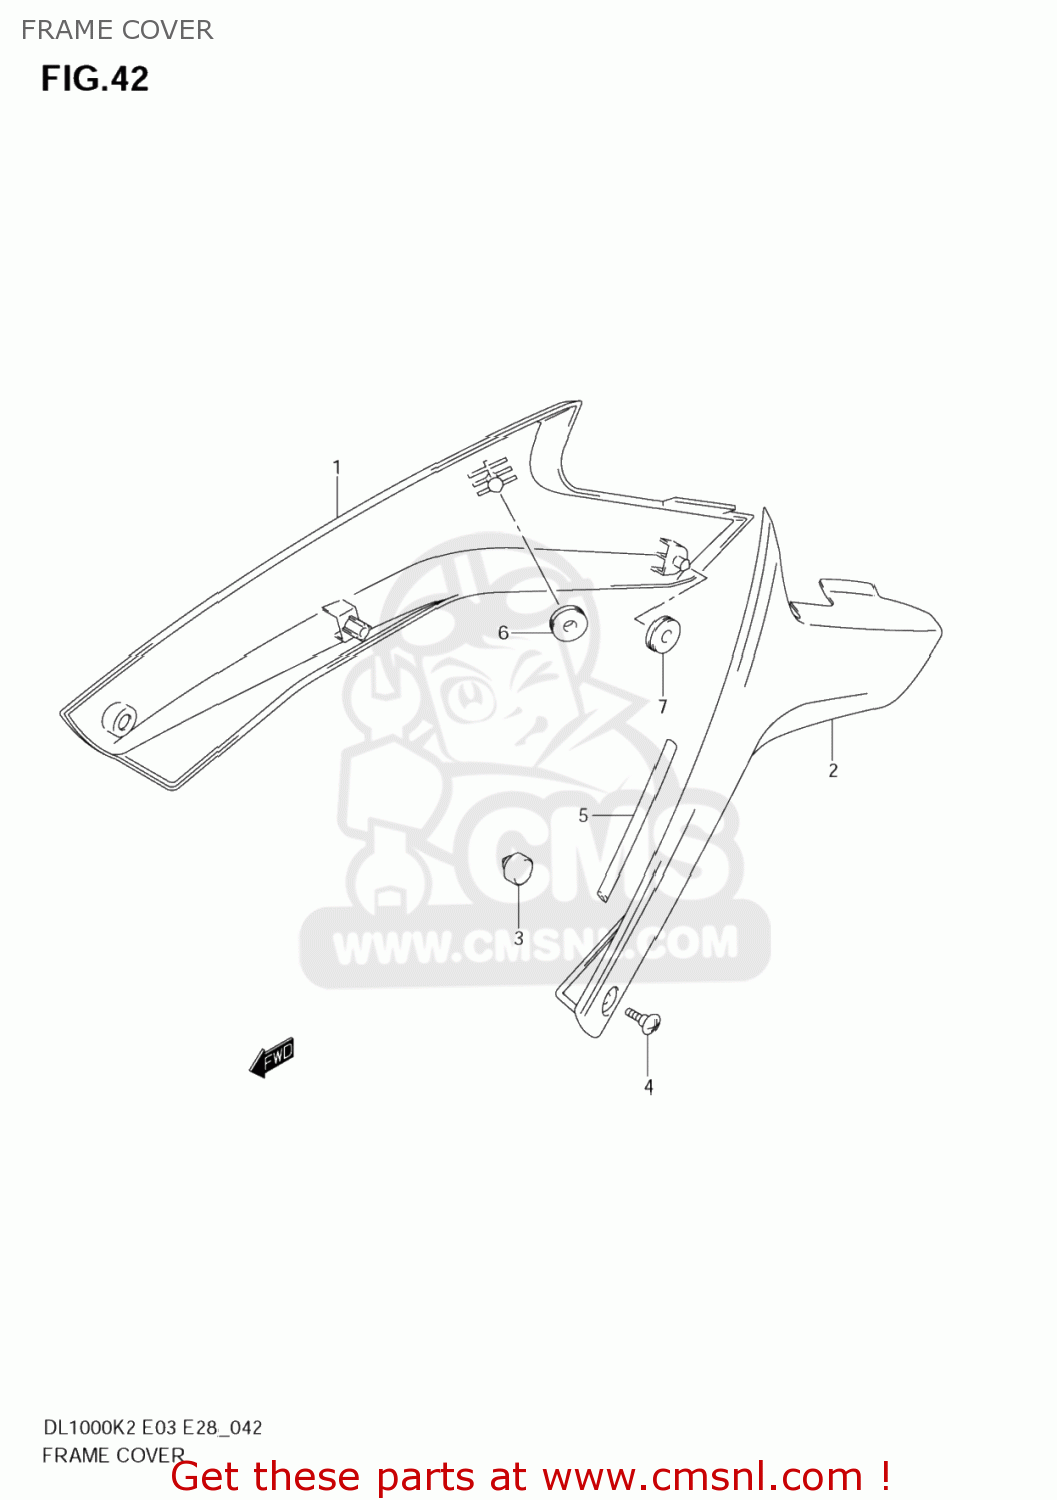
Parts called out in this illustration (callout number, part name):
1	COVER,FRAME,R(GRAY)
2	COVER,FRAME,L(GRAY)
3	CUSHION(11.5X22X20)
4	SCREW(6X16)
5	MOLDING
6	CUSHION
7	CUSHION
